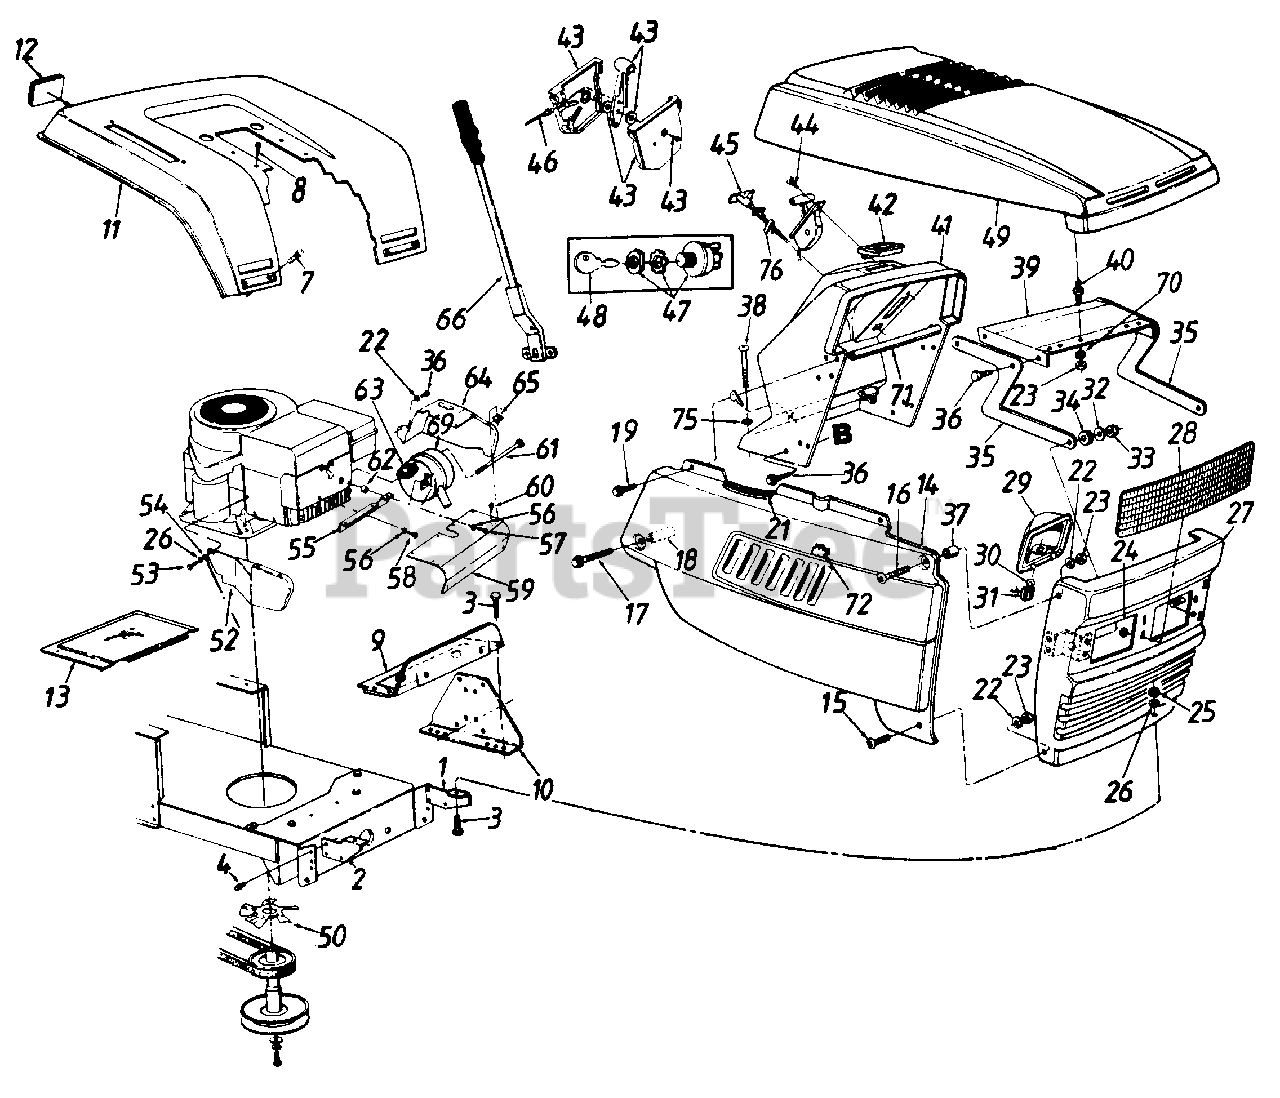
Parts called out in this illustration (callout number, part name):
1	Grille Mtg. Brkt.-L.H.
4	Hex Wash. Hd. Tap Scr. 5/16-18 x .5" Lg.
7	Carriage Bolt 1/4-20 x .5" Lg.
8	Hex Wash. Hd. Tap Scr. 5/16 x .75" Lg.
9	Support Bracket
13	Transmission Cover
14	Side Panel-R.H.
15	Truss Mach. Scr. 1/4-20 x .5" Lg.
16	Truss Mach. Scr. 1/4-20 x 1.0" Lg.
17	Hex Wash. TT-Tap Scr. 1/4-20 x 1.75" Lg.
18	Spacer .26" I.D. x 1.32"
19	Hex Rolling Tap Scr. 1/4-20 x .75" Lg.
21	Trim Strip-12" Lg.
22	L-Wash. 1/4" I.D.
23	Hex Nut 1/4-20 Thd.
24	Speed Nut 5/16" Thd.
25	Hex Nut 5/16-18 Thd.
26	L-Wash. 5/16" I.D.
29	Headlamp Housing
30	Headlamp
31	Twist Lock Lamp Socket
32	Bell-Wash. .345" I.D. x .88"
33	Hex L-Nut 5/16-18 Thd.
34	Rubber Washer
35	Hood Hinge
36	Hex Wash. Hd. B-Tap Scr. 1/4-20 x .5" Lg.
37	Spacer .262" I.D. x .31"
38	Carriage Bolt 1/4-20 x 1.25" Lg.
39	Hood Plate
40	Double Ended Stud 1/4-20 Thd.
41	Dash
42	Ammeter
43	Throttle Control Box Ass'y.
44	Mach. Scr. #10 x .44" Lg.
45	Choke Control 29" Lg.
46	Throttle Control Wire
47	Ignition Switch
48	Ignition Key
52	Muffler Heat Shield-R.H.
53	Truss Mach. Scr. 5/16-18 x .75" Lg.
54	Ground Wire
55	Heat Shield Bracket
56	Spr. Wash. 1/4" I.D.
57	Hex Bolt 1/4-20 x .85" Lg.
58	Hex Bolt 1/4-20 x 3/8" Lg.
59	Muffler Heat Shield-Front
60	Hex AB-Tap Scr. #10 x 5" Lg.
61	Shoulder Bolt
62	Spacer
63	Exhaust Gasket
64	Muffler Heat Shield-L.H.
65	Speed Nut #10-24 Thd.
66	Lift Handle
69	Muffler
70	Bell-Wash. .265" I.D. x .75"
71	Grille Support Tube
72	Mounting Clamp
75	Retaining Nut
76	Choke Retainer
